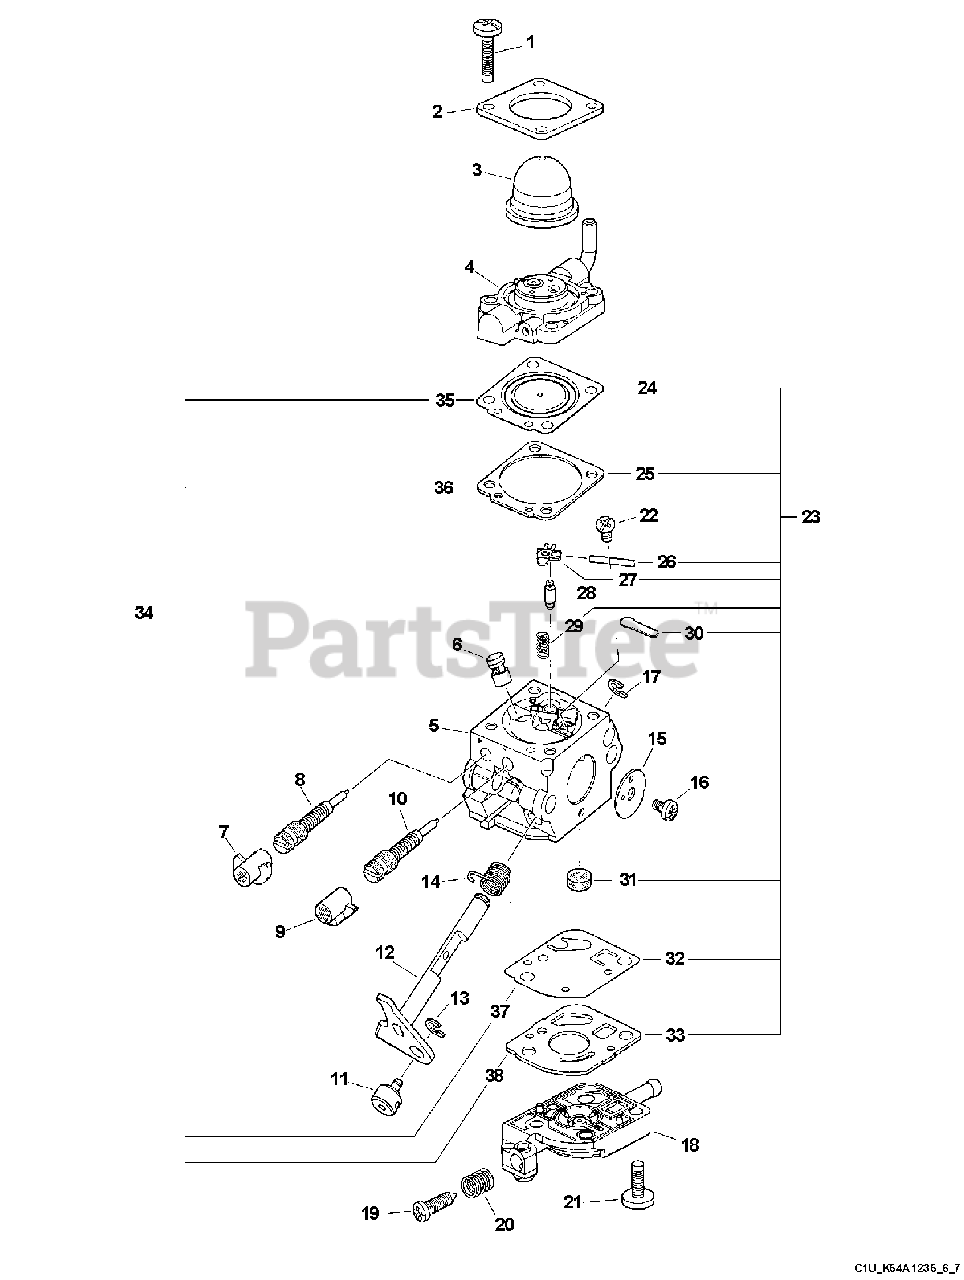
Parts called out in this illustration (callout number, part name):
1	SCREW, RETAINER
2	RETAINER, PURGE BULB
3	BULB, PURGE
4	BASE, PURGE
5	BODY, CARBURETOR
6	NOZZLE, CHECK VALVE
7	CAP, LIMITER
8	NEEDLE - HIGH SPEED
9	CAP, LIMITER
10	NEEDLE - LOW SPEED
12	SHAFT, THROTTLE
13	RING, RETAINING
14	SPRING, RETURN
15	VALVE, THROTTLE
17	RING, RETAINING
18	BASE, PURGE
19	SCREW, IDLE ADJUST
20	SPRING, IDLE ADJUST
21	SCREW, PUMP COVER
22	SCREW, METERING LEVER PIN
23	REPAIR KIT
24	DIAPHRAGM, METERING
25	GASKET, DIAPHRAGM
26	PIN, METERING LEVER
27	LEVER, METERING
28	VALVE, INLET NEEDLE
29	SPRING, METERING LEVER
30	PLUG, WELCH
31	STRAINER
32	DIAPHRAGM, PUMP
33	GASKET, PUMP
34	DIAPHRAGM/GASKET KIT
35	DIAPHRAGM, METERING
36	GASKET, DIAPHRAGM
37	DIAPHRAGM, PUMP
38	GASKET, PUMP
